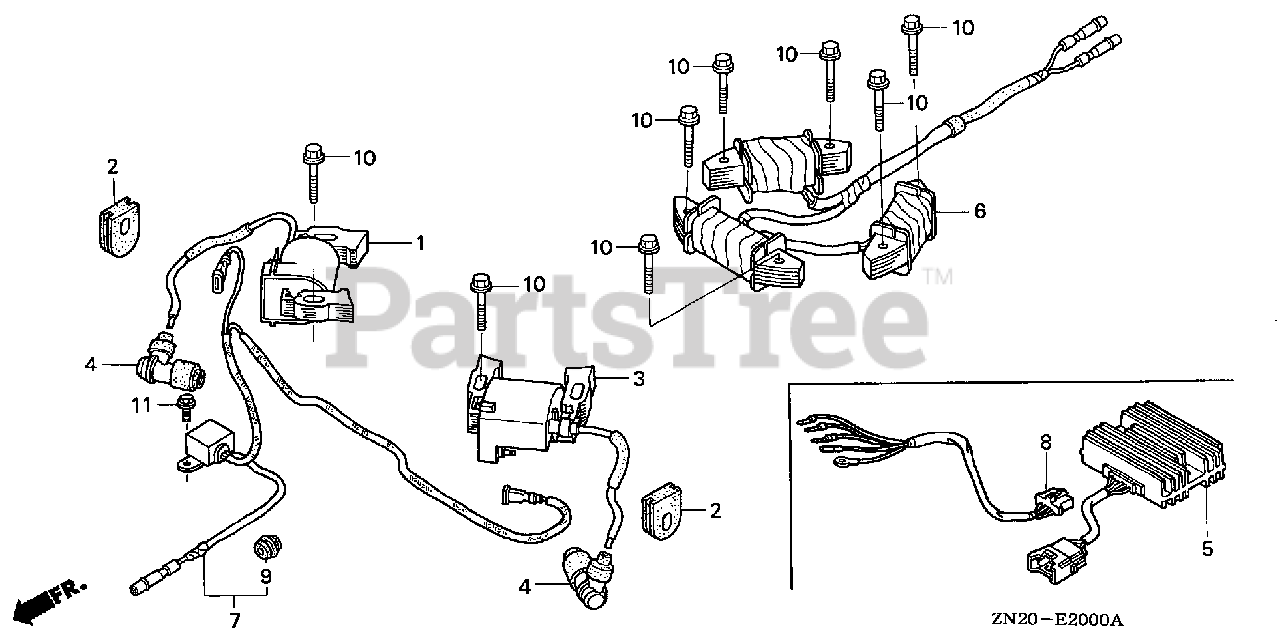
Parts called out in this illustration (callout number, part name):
1	COIL ASSY., IGNITION
2	GROMMET, IGNITION WIRE
3	COIL ASSY., IGNITION
4	CAP ASSY., NOISE SUPPRESSOR
5	RECTIFIER ASSY., REGULATOR (20A)
6	COIL ASSY., CHARGE (12V/20A)
7	DIODE ASSY., ENGINE STOP
9	GROMMET, TOOL
10	BOLT, FLANGE (6X32) (CT200)
11	BOLT, FLANGE (6X8)
